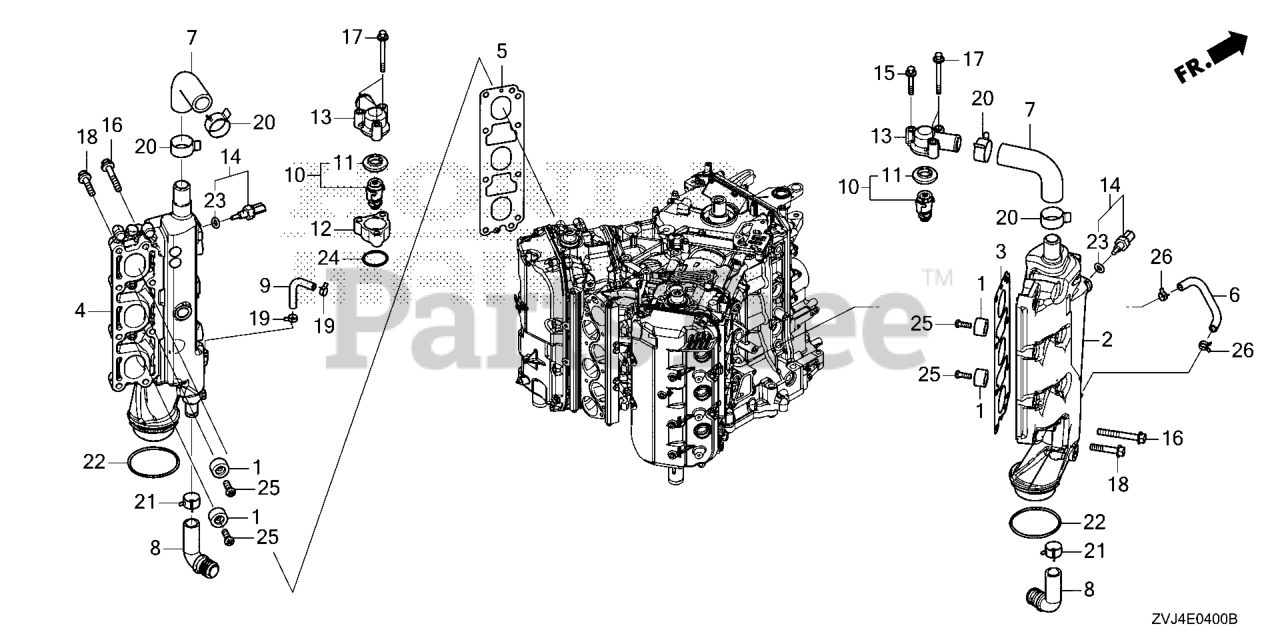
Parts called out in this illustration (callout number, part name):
1	METAL, ANODE
2	MANIFOLD, R. EX. *NH8* (DARK GRAY)
3	GASKET, R. EX. MANIFOLD
4	MANIFOLD, L. EX. *NH8* (DARK GRAY)
5	GASKET, L. EX. MANIFOLD
7	TUBE, WATER RELIEF
8	TUBE, WATER
9	TUBE, L. WATER RETURN
10	THERMOSTAT ASSY.
11	RUBBER, RING
12	SPACER, THERMOSTAT COVER *NH8* (DARK GRAY)
12	SPACER *NH8*
13	COVER, THERMOSTAT *NH8* (DARK GRAY)
13	COVER *NH8*
14	SENSOR ASSY., WATER TEMPERATURE
15	BOLT, FLANGE (6X35)
16	BOLT, FLANGE (8X60)
17	BOLT, FLANGE (6X60)
18	BOLT, FLANGE (8X40)
19	CLAMP, TUBE (D10.5) (ENGINE NO.)
20	CLAMP, TUBE (D29)
21	CLAMP, TUBE (D21)
22	O-RING (66.4X3.1)
23	O-RING (9.5X1.9)
24	O-RING (31.5X2.4) (ARAI)
25	BOLT, FLANGE (6X18)
25	SCREW, PAN (6X18)
26	CLAMP D12.5, TUBE
26	CLAMP, TUBE (D10.5) (ENGINE NO.)
